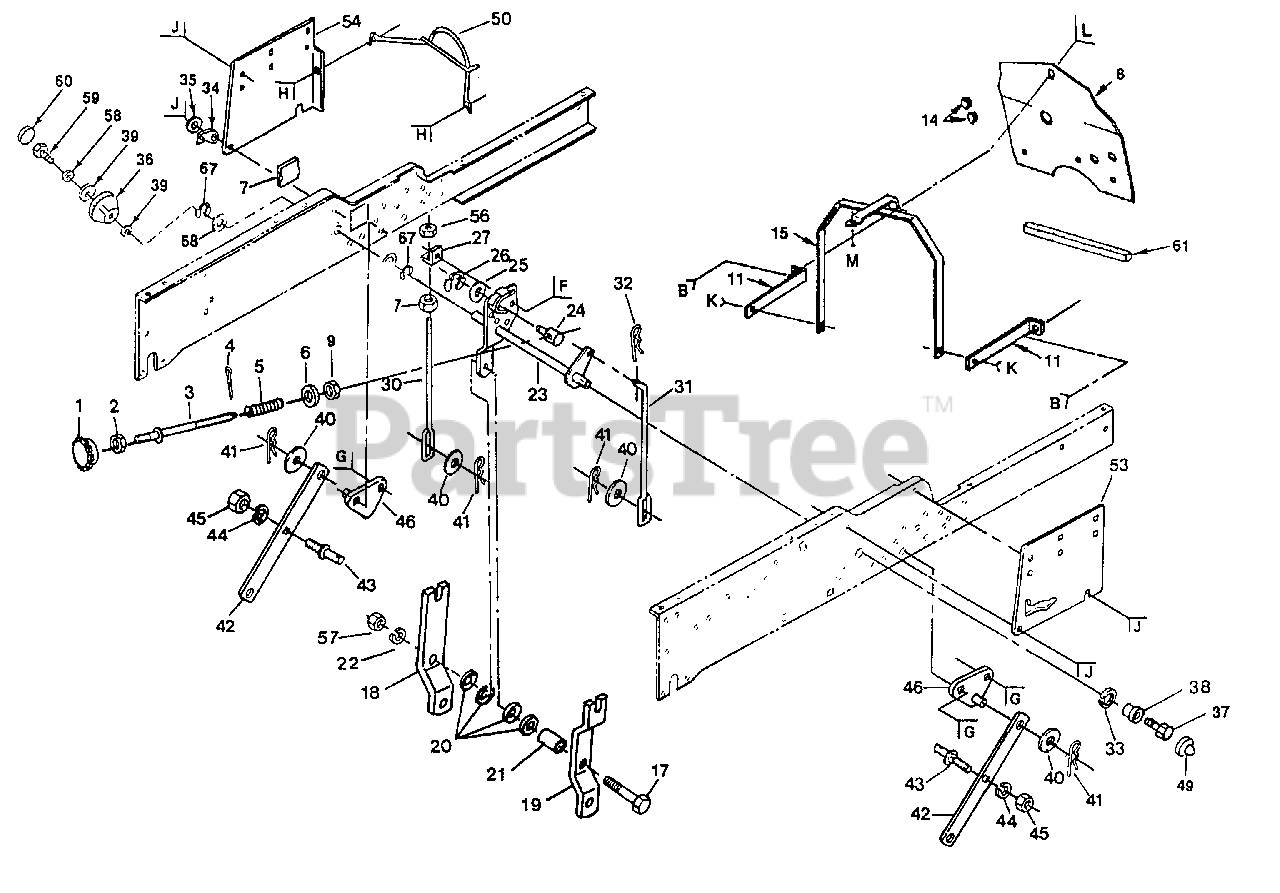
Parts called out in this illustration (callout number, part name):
1	Handle, Adjust, Lift
2	Nut, Hex Jam, 3/8-16
3	Rod, Adjust, Lift
4	Pin, Cotter 3/32 x 3/4
5	Spring
6	Washer 13/32 x 5/8 x 16 Ga.
7	Cover, Access
8	Shield, Heat, Rear
9	Nut, Special
11	Brace, Heat Shield
14	Grommet
15	Support Asm. Dash
17	Bolt, 3/8-16 x 1-3/4
18	Brkt. Lift LH
19	Brkt. Lift RH
20	Washer, 17/32 x 1-1/2 x 10 Ga.
21	Tube .384 x 1/2 x 1-1/4
22	Lockwasher, 3/8
23	Shaft, Lift
24	Trunnion, Stop Depth
25	Washer, 15/32 x 3/4 x 16 Ga.
27	Brkt. Lift LH
30	Link Lift LH
31	Link Lift RH
32	Retainer, Spring
33	Washer, Nylock
34	Pointer, Height Indicator
35	Washer, Nylon
36	Scale, Height Indicator
37	Bolt, Hex 3/8-16 x 1
38	Hub, Lift Shaft
39	Washer 11/32 x 1 - 1/2 x 10 Ga.
40	Washer 17/32 x 1 x 16 Ga.
41	Retainer, Spring
42	Arm Suspension
43	Stud, Pivot Center
44	Washer, Lock 1/2
45	Nut, Hex, 1/2-13
46	Brkt. Suspension, Mower
49	Cap, Spring
50	Guard, Belt, Engine
53	Panel, Side RH
54	Panel, Side LH
56	Nut, Lock, 3/8-16
57	Nut, Hex 3/8-16
58	Washer, Lock Hvy. Helical Spring
59	Bolt, Hex Fin 5/16 - 18 x 1
60	Plug, Hole
61	Strip, Foam
68	Washer 29/32 x 1 - 1/4 x 16 Ga.
